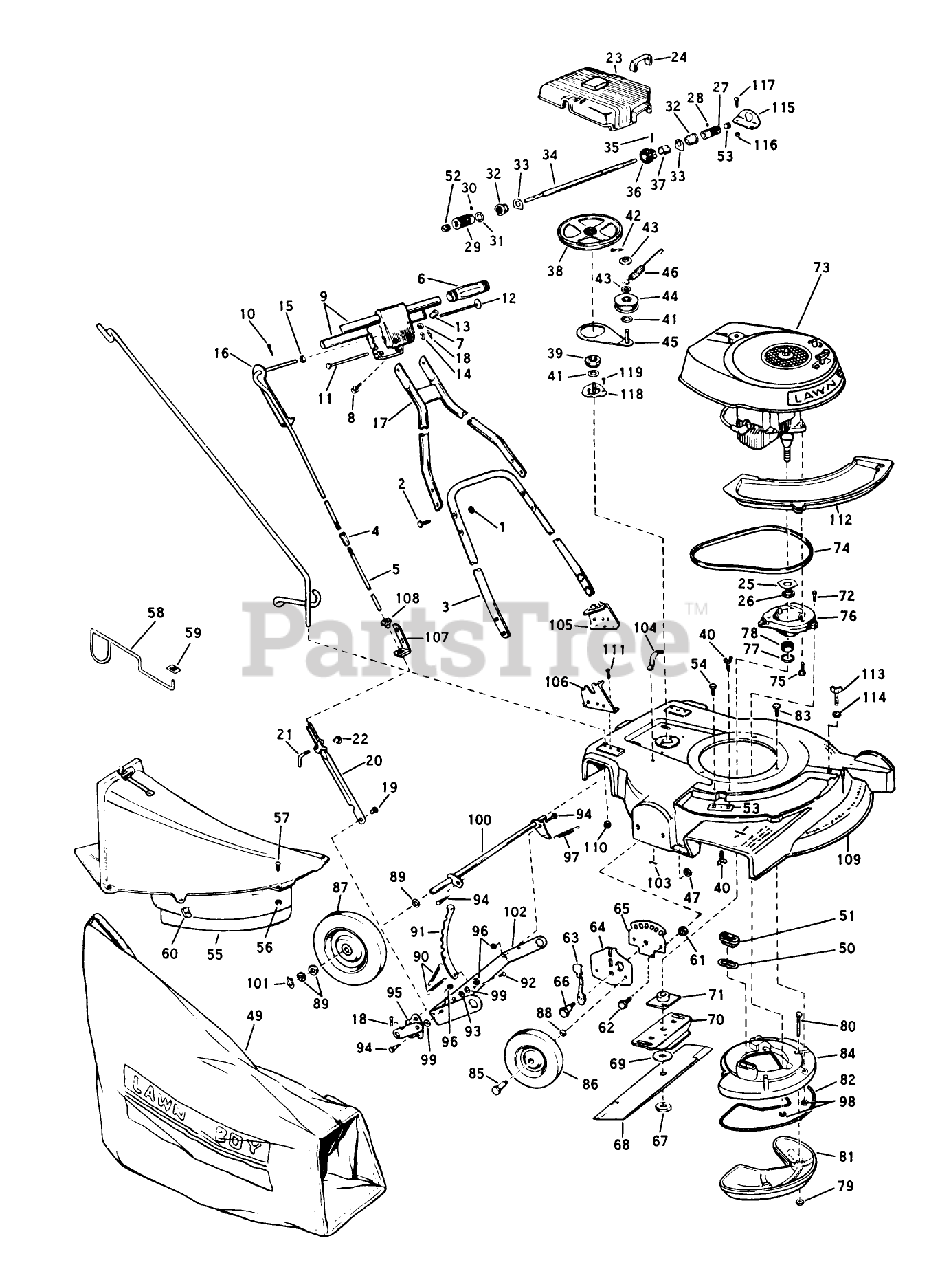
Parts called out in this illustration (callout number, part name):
10	Pin-Cotter
38	PULLEY&OILER FELT (13)
49	89802 LB WHOLE GOODS
50	GASKET S
52	GREASE PLUG
55	Chute Skirt Assembly (Includes Hardware)
60	SPEED NUT ARDEN
67	NUT-BLADE
71	PLATE AND COLLAR ASM
79	LOCKNUT E
85	BOLT WHEEL
88	WASHER WROUGHT
89	WASHER
94	BOLT RB&W
96	STOP NUT
99	WASHER S
101	RETAINING RING
111	SCREW S
